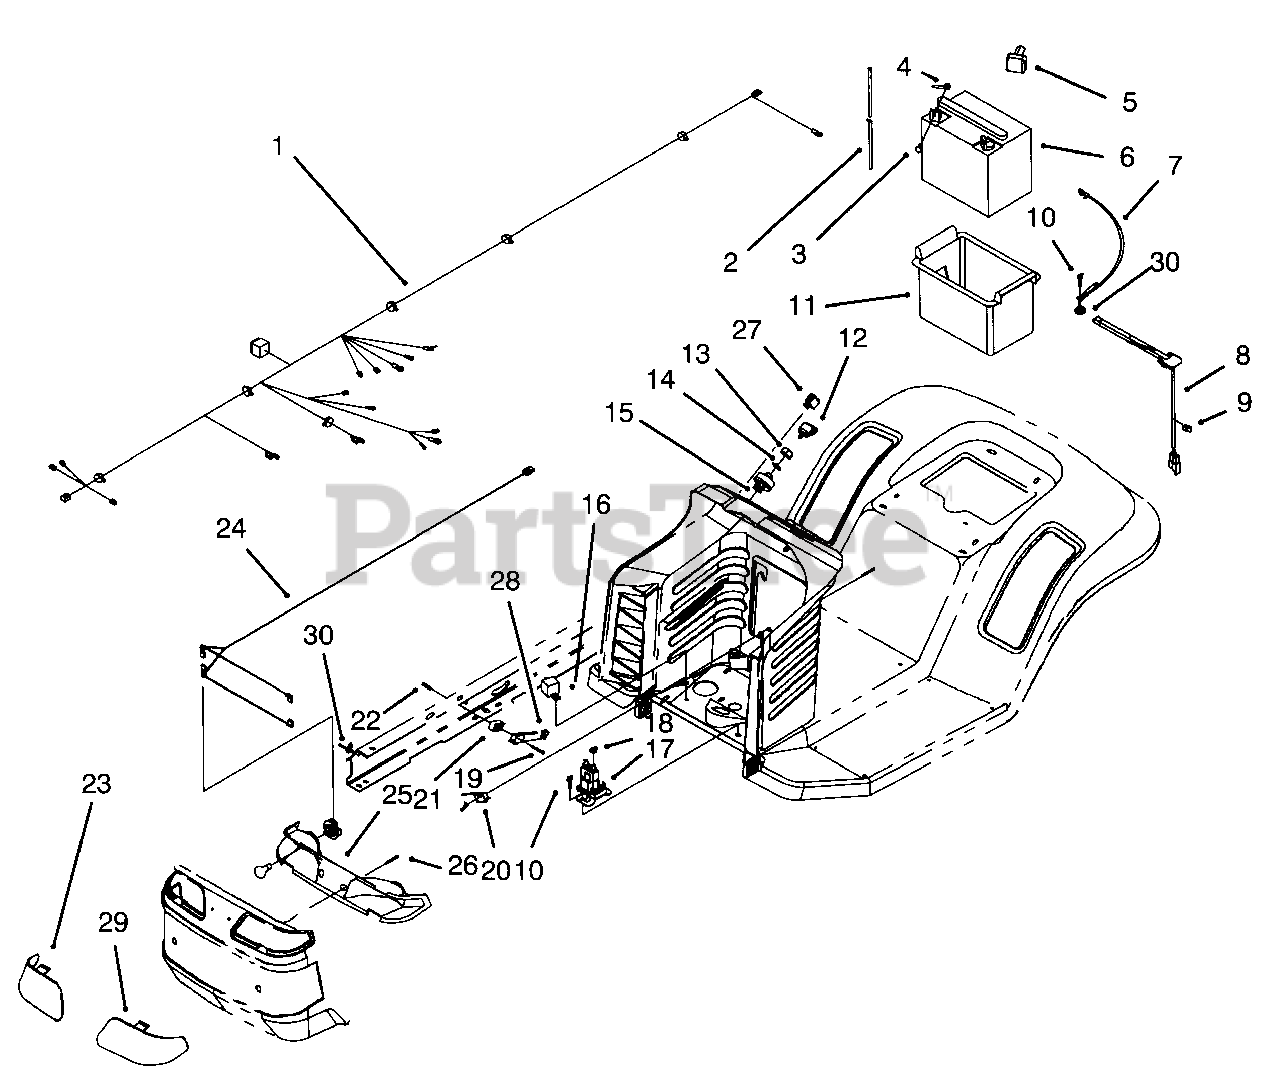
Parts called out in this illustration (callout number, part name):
1	Harness-Wire
2	Vent-Tube
3	Screw-Hex Hd. Cap
5	Boot-Battery Terminal
6	Battery-7 Plate
7	Cable-Battery Negative
8	Switch-Seat
9	Clip-Wire Retainer
10	Screw-Hex Hd. Thr'd Forming
11	Box-Battery
12	Key-Ignition
14	Washer-Lock
15	Switch-Ignition (Incl. Ref. #13 & 14)
17	Solenoid
18	Nut-Keps
19	Screw-Phillips Hd.
20	Switch-Micro
21	Spacer-Microswitch
23	Lens-R.H.
24	Harness-Wire
25	Reflector & Lamp
26	Screw-Plastite
27	Switch-Rocker
28	Seal-Plunger
29	Lens-L.H.
30	Washer-Lock
